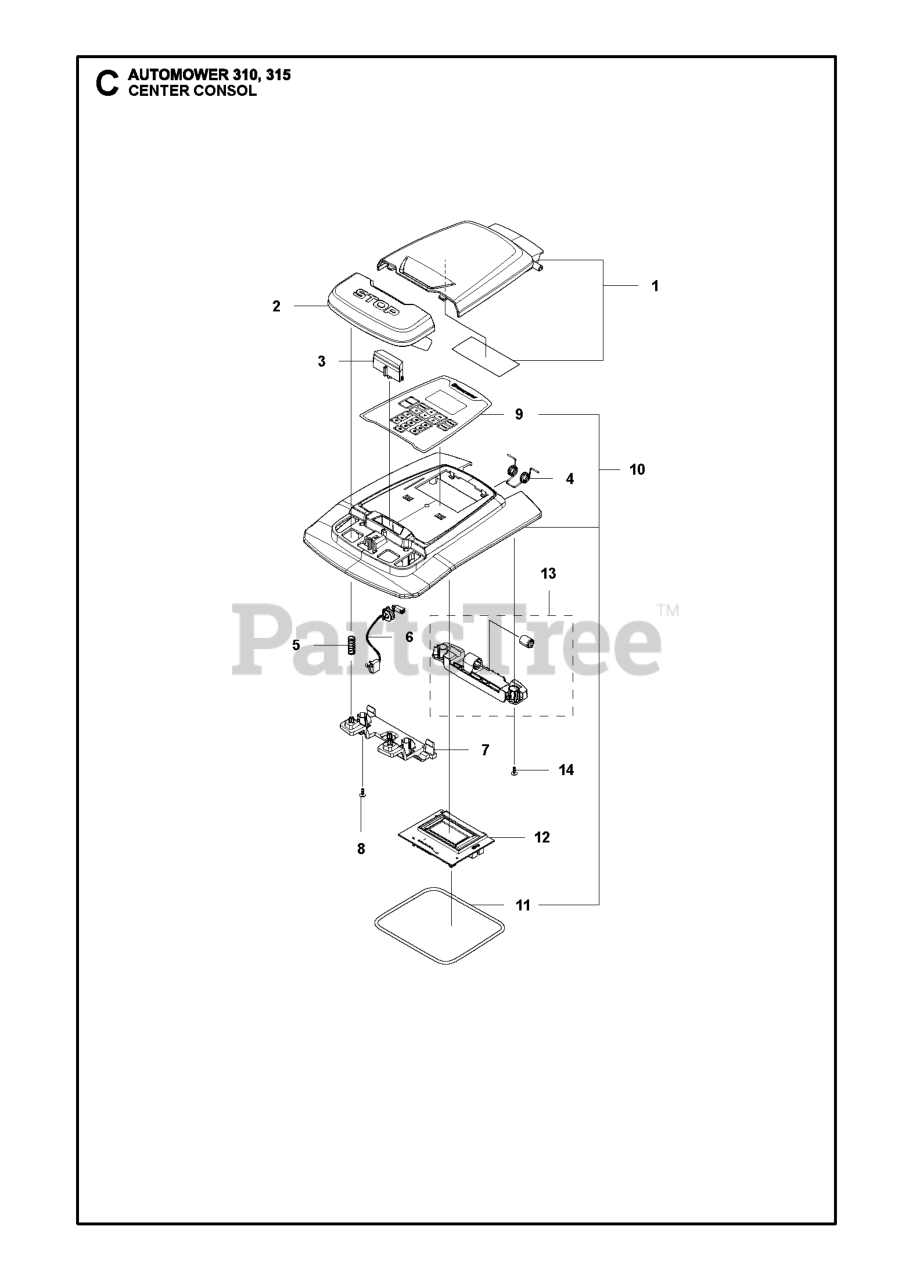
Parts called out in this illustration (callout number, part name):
2	BUTTON STOP
4	TORSION SPRING DT=1,3MM
5	SPRING LOCK STOP BUTTON
6	SWITCH STOP BUTTON NO ANCHOR
7	SUPPORT REAR
8	SCREW 14MM
9	KEYBOARD 2.1" DISPLAY
10	COVER KIT 2.1" DISPLAY
11	SEALING STRIP P15 UPPER
12	PCB ASSY MMI
13	SUPPORT KIT
14	SCREW 14MM
